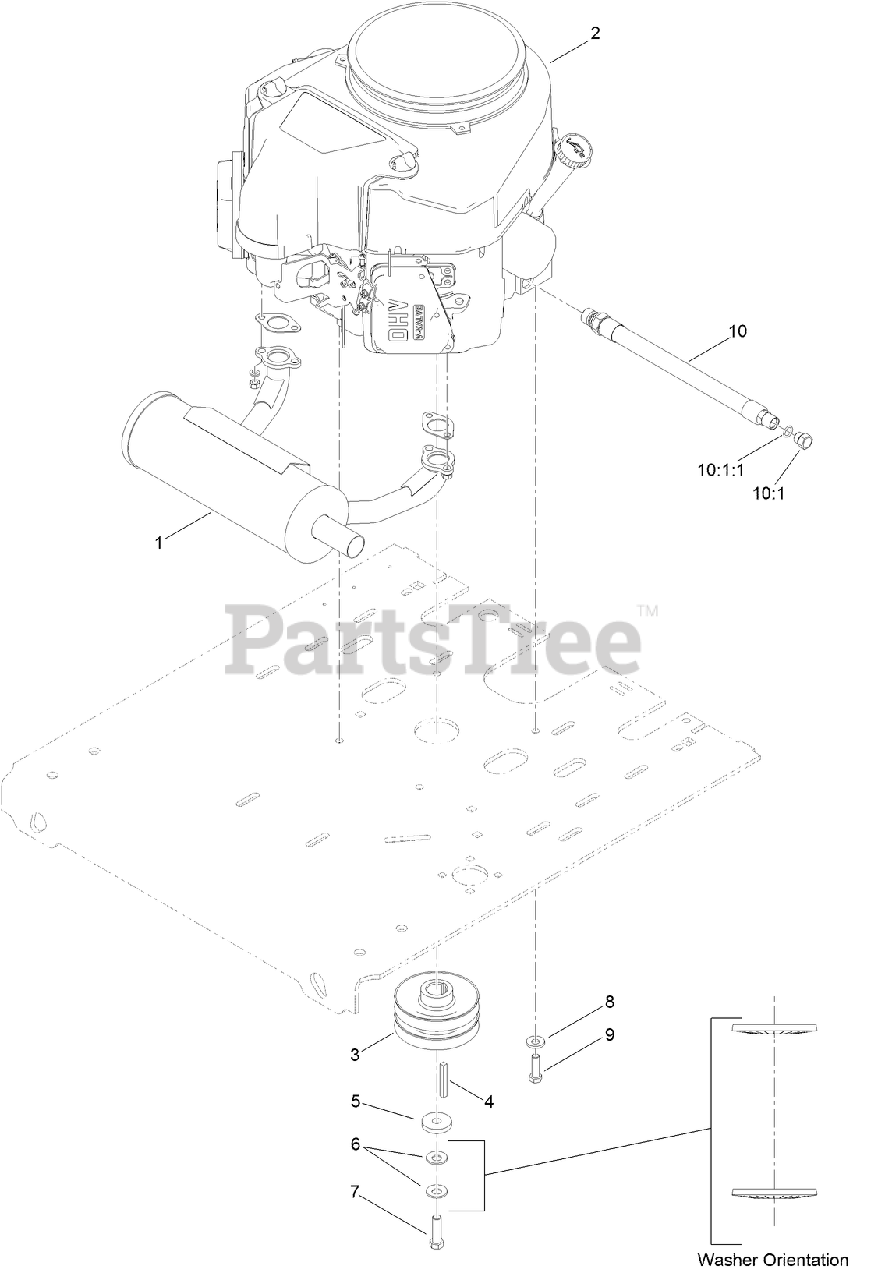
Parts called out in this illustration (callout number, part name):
1	MUFFLER-HORIZONTAL
3	PULLEY
5	WASHER-CLUTCH
6	WASHER-SPRING
7	SCREW-HH
8	WASHER-BELLEVILLE
9	SCREW-HH
10	ENGINE OIL DRAIN HOSE ASM
10:1	PLUG-HH
10:1:1	O-RING
